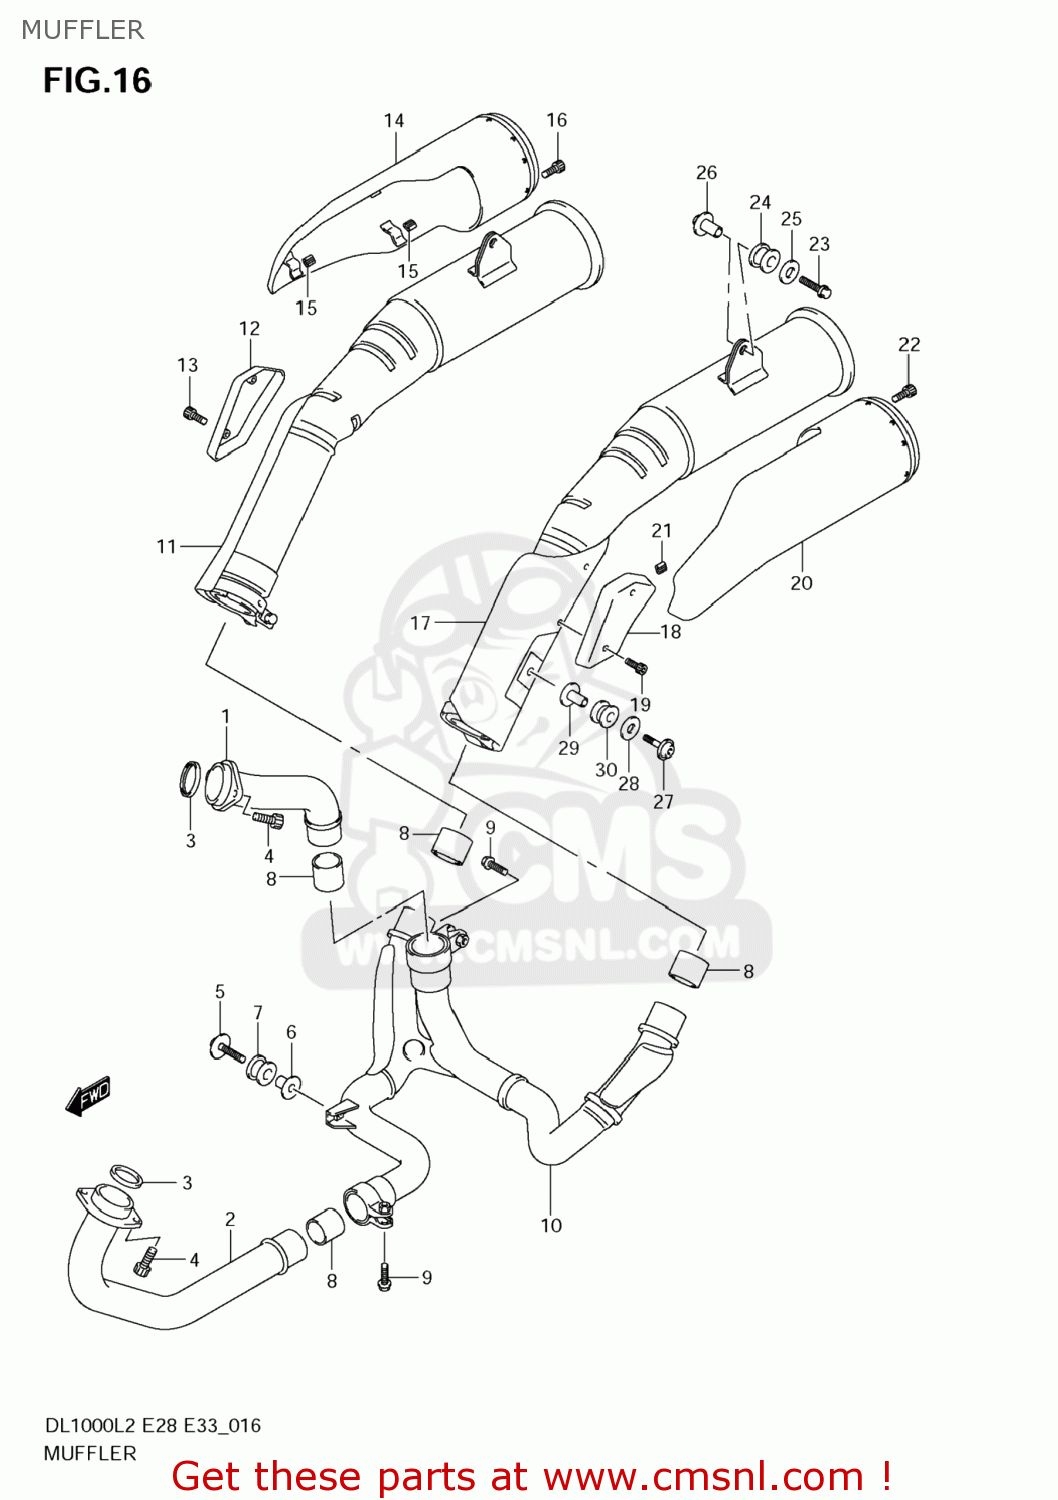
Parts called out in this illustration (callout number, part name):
1	PIPE,EXHAUST,R
2	PIPE,EXHAUST,L
3	GASKET,EXHAUST PIPE (NAS)
4	BOLT(8X25)
5	BOLT(8X45)
6	SPACER(8.6X12X24.2)
7	CUSHION
8	CONNECTOR,EXHAUST,R
9	BOLT(8X40)
10	PIPE,EXHAUST CTR
11	MUFFLER,R
12	PROTECTOR,MUFFLER COVER FR,R
13	BOLT
14	COVER,MUFFLER,R
15	GROMMET,MUFFLER COVER
16	BOLT(6X10)
17	MUFFLER,L
18	PROTECTOR,MUFFLER COVER FR,L
19	BOLT
20	COVER,MUFFLER,L
21	GROMMET,MUFFLER COVER
22	BOLT(6X10)
23	BOLT(8X45)
24	CUSHION
25	WASHER(8.5X33X1.5)
26	NUT,MUFFLER SUPPORT
27	BOLT(8X30)
28	WASHER(8.5X26X1.6)
29	SPACER(8.6X12X17.5)
30	CUSHION
